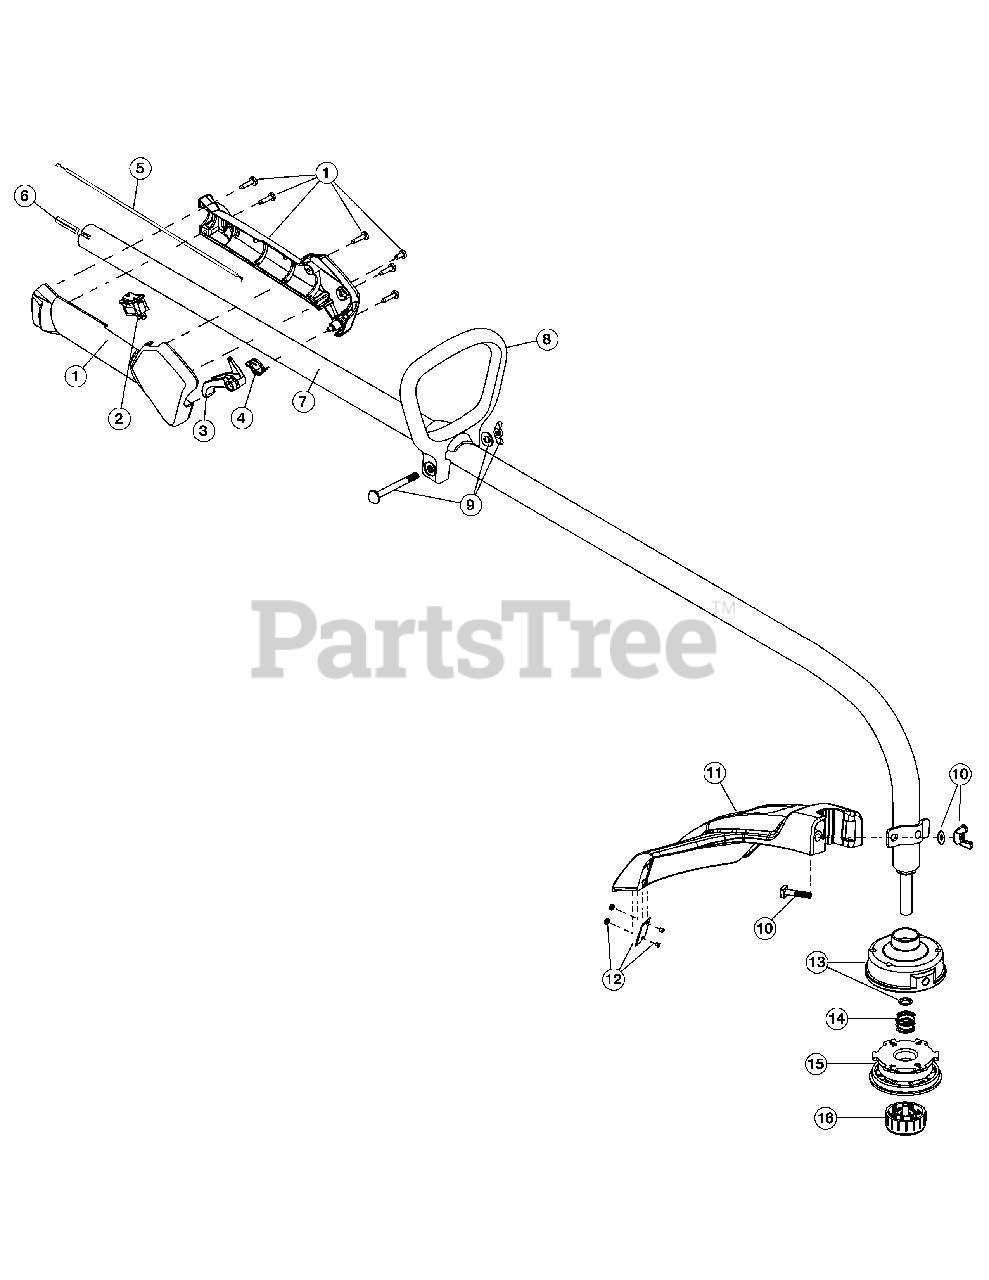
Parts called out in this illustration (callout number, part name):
1	Throttle Housing Assembly (includes 2-4)
3	Throttle Trigger
4	Throttle Trigger Spring
5	Throttle Cable
6	Flexible Drive Shaft
7	Drive Shaft Housing
8	D-Handle (includes 9)
9	Handle Hardware
10	Guard Mounting Hardware
11	Guard (includes 12)
12	Blade Assembly
13	Outer Reel w/Retainer
15	Inner Reel
